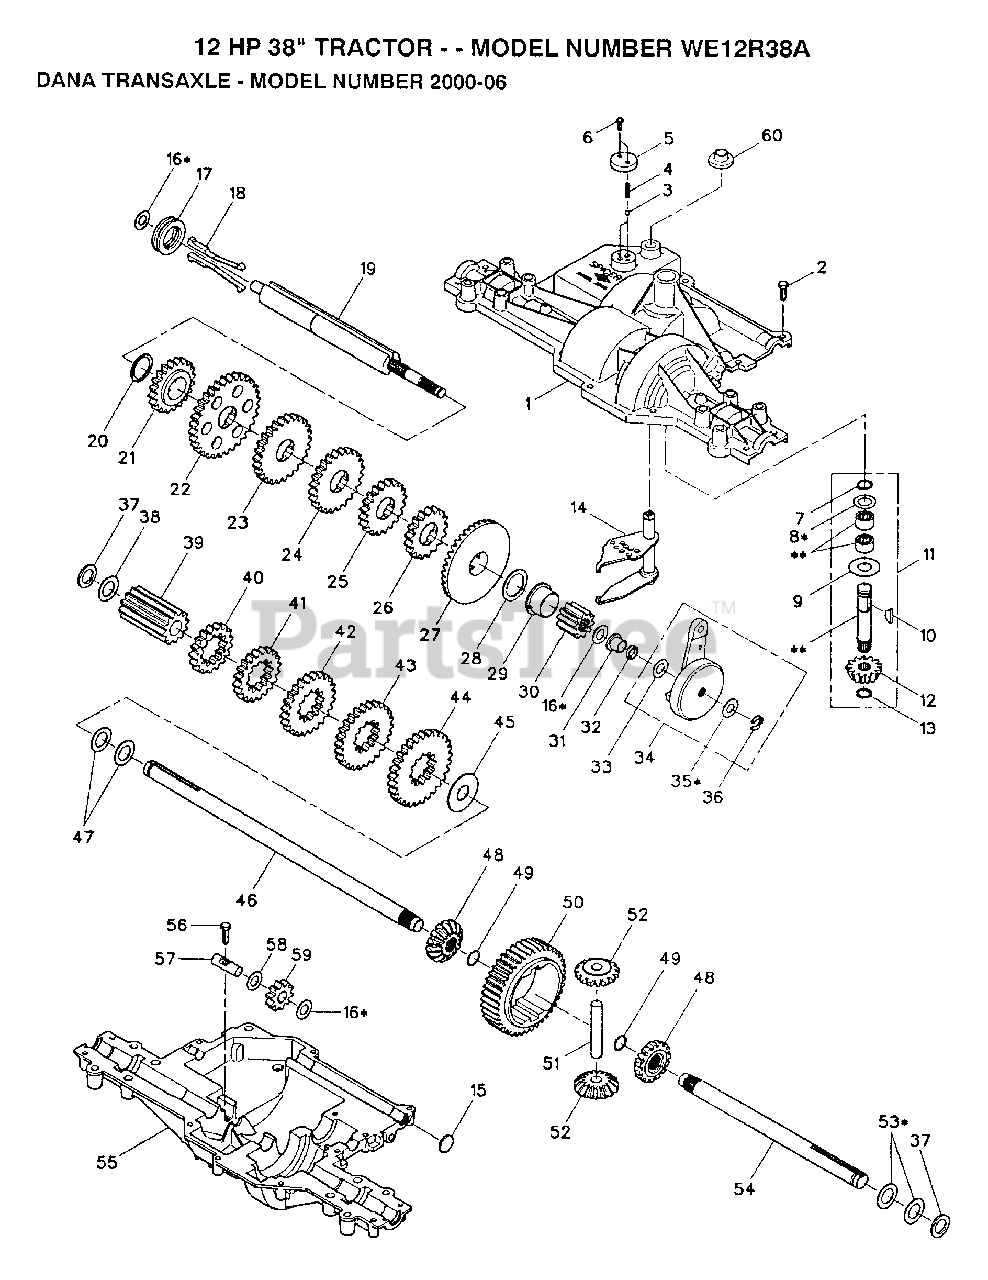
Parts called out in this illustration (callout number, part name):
1	HOUSING. UPPER
4	SPRING, DETENT
5	COVER, DETENT
6	SCREW, TAPPING, LARGE #8-32 X .50
7	RETAINING RING LT
8	ASM KIT SHIM 4689
9	WASHER T
10	WOODRUFF KEY
11	ASSEMBLY, KIT, INPUT SHAFT
12	PINION,, BEVE, 13 TEETH
13	RING, RETAINING
14	ASSEMBLY, SHIFTER
16	ASSEMBLY, KIT, SHIM, .500 SHAFT
18	ASSEMBLY, KIT, CLUTCH KEYS
19	SHAFT, DRIVE
20	"RING,RETAINING LT"
21	GEAR, SPUR, 20 TEETH
22	GEAR , SPUR, 32 TEETH
23	GEAR, SPUR, 26 TEETH
24	GEEAR, SPUR, 24 TEETH
25	GEAR, SPUR, 20 TEETH
26	GEAR, SPUR, 17 TEETH
27	GEAR, BEVEL, 39 TEETH
28	WASHER, PLAIN 1,135 X 1.56 X .062
29	BEARING, FLANGE
30	GEAR, SPUR, 10 TEETH
31	BEARING, FLANGE
33	WASHER T
34	ASSEMBLY, KIT CONE BRAKE
35	ASSEMBLY, KIT, SHAM .464 SHAFT
37	NEOPRENE WASHER
38	WASHER 062
39	GEAR, SPUR, 12 TEETH
40	GEAR, SPUR, 17 TEETH
41	GEAR, SPUR, 20 TEETH
42	GEAR, SPUR, 24 TEETH
43	GEAR, SPUR, 26 TEETH
44	GEAR SPUR, 29 TEETH
45	WASHER, PLAIN, .758 X 1.88 X .062
47	WASHER 031
48	GEAR 15T T
49	"RING,RETAINING LT"
50	GEAR, SPUR, 41 TEETH
51	SHAFT T
52	GEAR 1ST T
53	ASM KIT SHIM
55	HOUSING, LOWER
57	SHAFT, IDLER
58	WASHER T
59	GEAR, SPUR, 10 TEETH
60	SHIFTER BOOT
